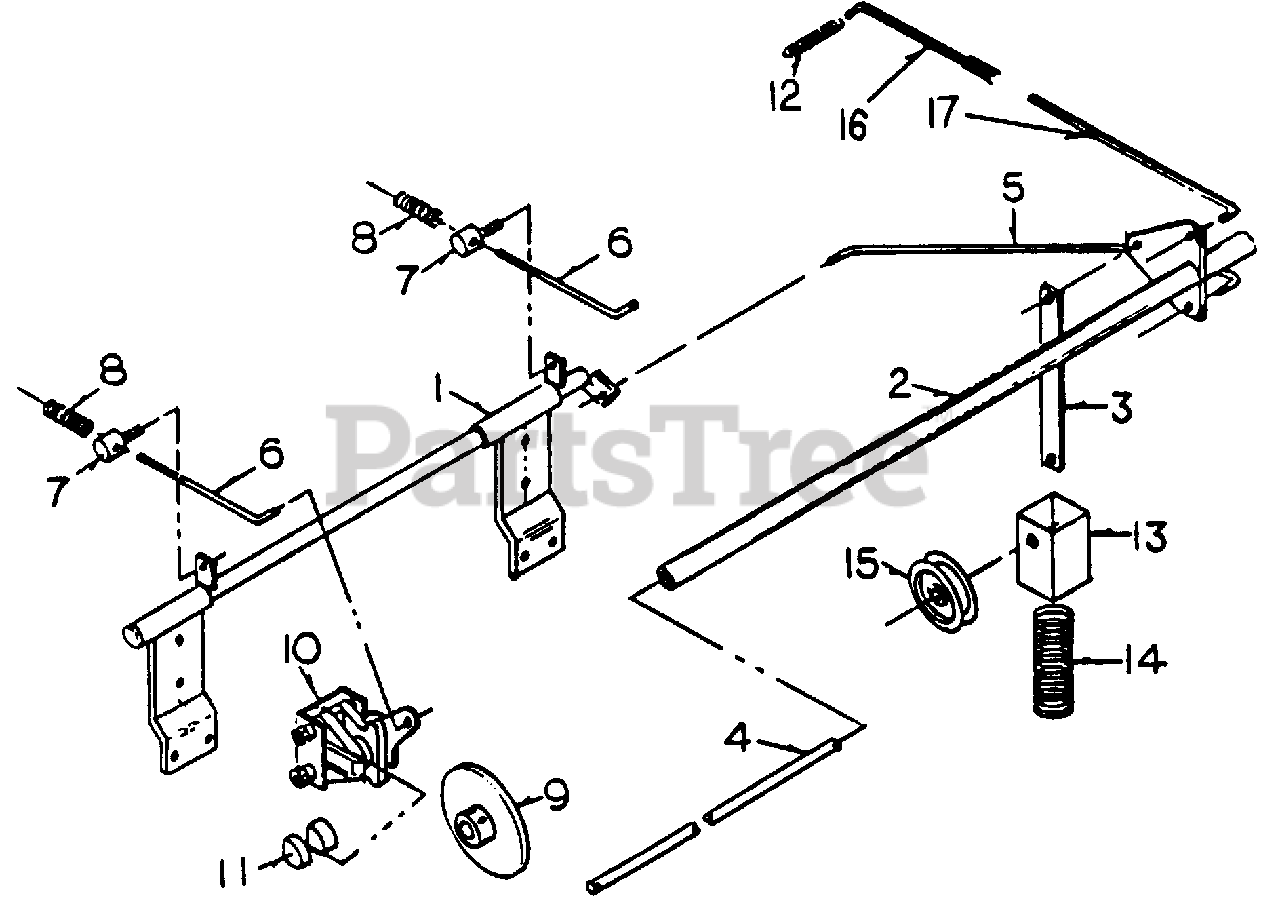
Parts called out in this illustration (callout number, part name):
1	Brake Mount & Cross Rod Ass'y.
2	Brake Clutch Cross Rod
3	Cross Rod to Idler Pulley Linkage
4	Cross Bar Pin
5	Crss Rod to Brake Linkage
7	Callper Rod Collar
8	Brake Caliper Spring
10	Brake Assembly
12	Brake Pedal Spring
13	Spring Loaded Idler Mount
14	Transmission Belt Idler Spring
15	Idler Pulley
16	Brake Rod, Adjustable
